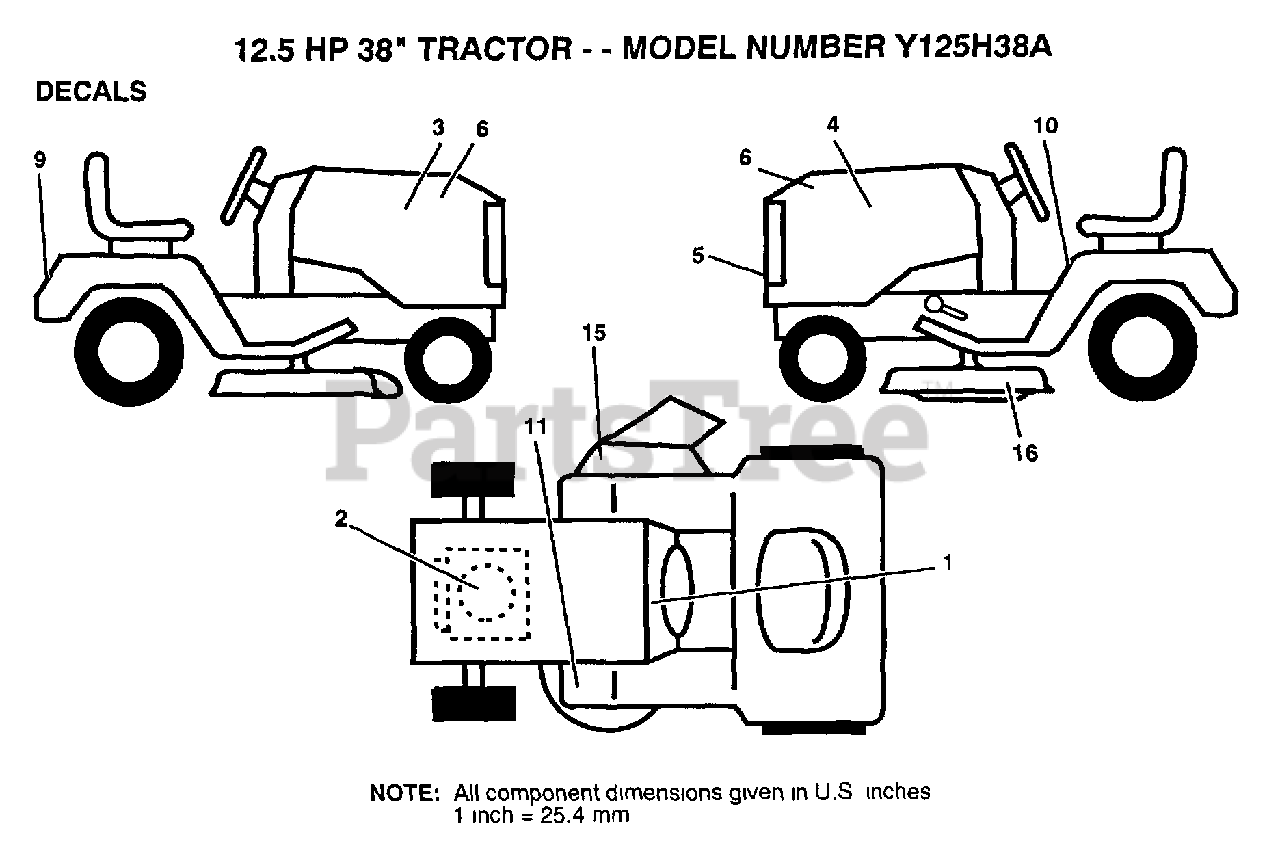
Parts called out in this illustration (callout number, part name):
10	DECAL CAUTION
11	DECAL T
15	DECAL WARNING
16	DECAL YT
